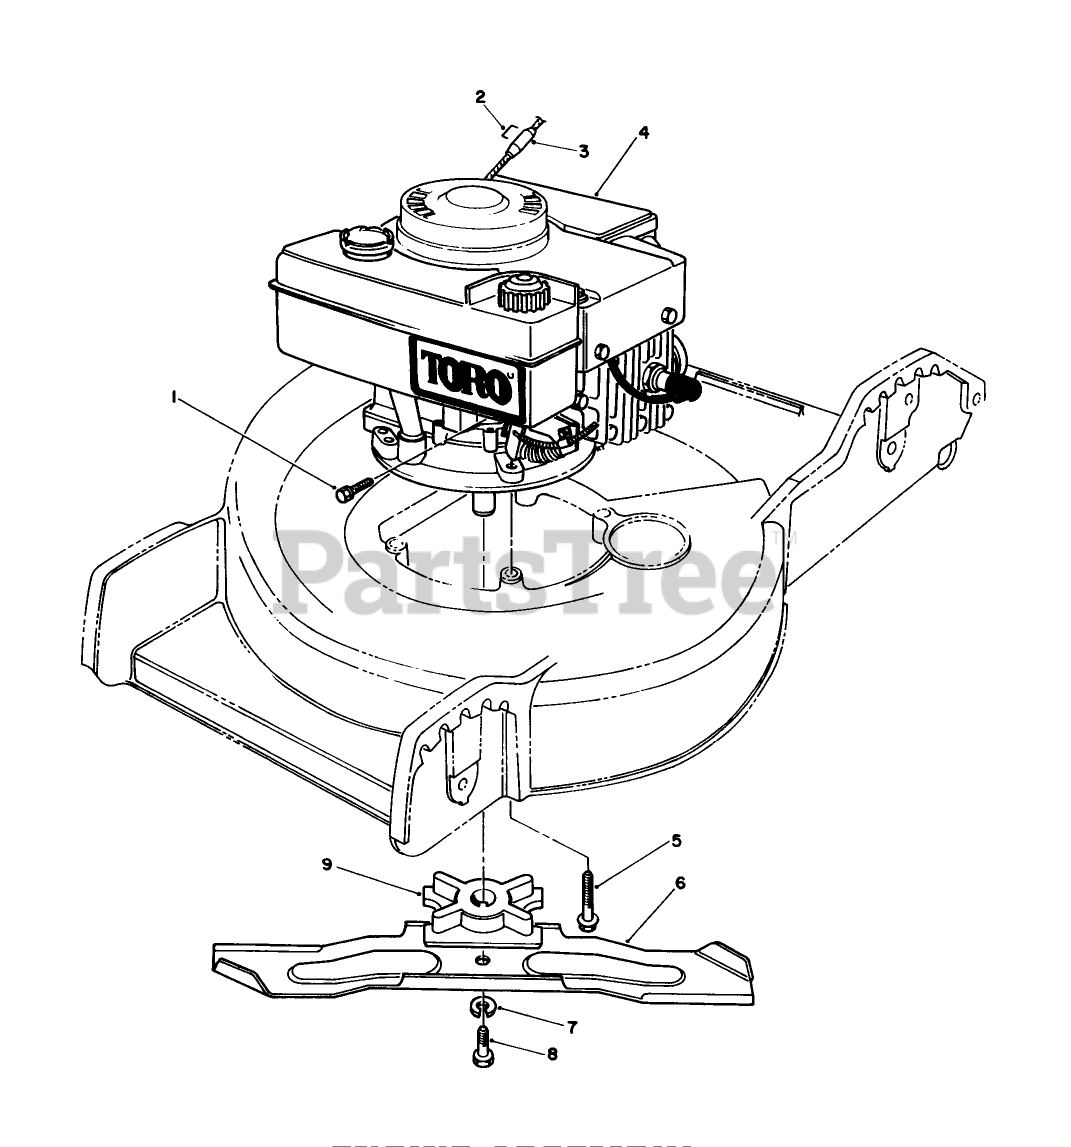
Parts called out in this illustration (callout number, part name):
1	SCREW-HH
2	Staple
3	Stop-Rope
5	3/8-16 X 2 CAPSCREW
6	Blade
7	WASHER-LOCK
8	SCREW-HH
9	BLADE RETAINER
